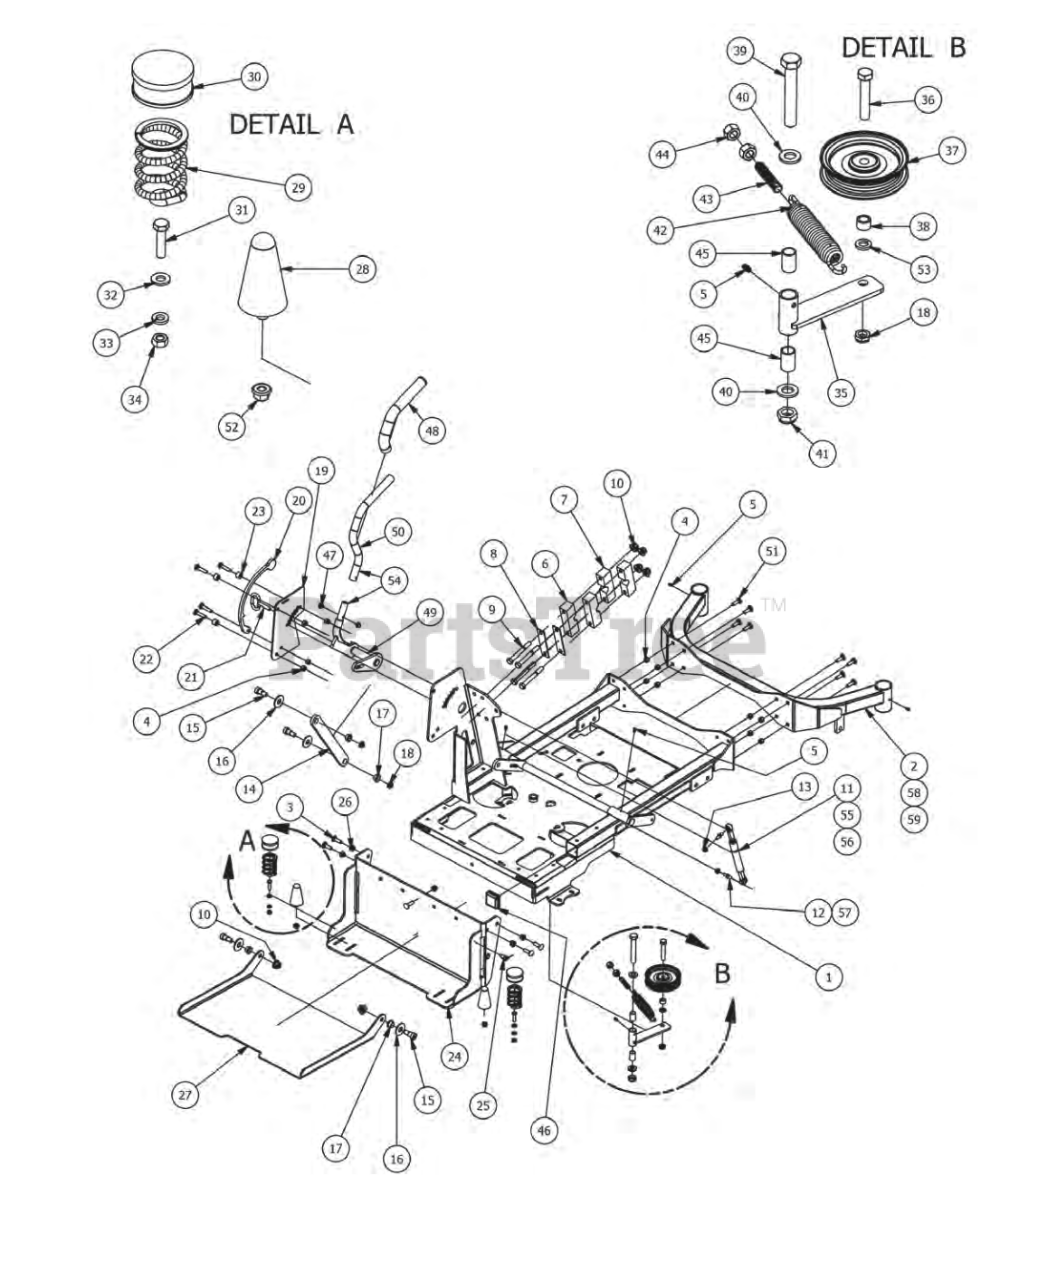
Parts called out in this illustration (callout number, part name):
1	2015 Stand-On Frame
2	48" Front End (2015 Stand-On)
3	3/8" x 1 1/4" Carriage Bolt
4	3/8 Nylock Nut
5	1/4" Press in Grease Fitting
6	Two Piece Pillow Block (Male)
7	Two Piece Pillow Block (Female)
8	Two Piece Pillow Block Strap
9	1/2" x 4" Bolt (Grade 8)
10	1/2-13 Nylon Flange Nut-Orange
11	200 lb Gas Spring- 54" Deck outlaw
12	10mm Damper Ball Stud-Steering
13	5/16" Flange Nut
14	Stand On Flat Linkage Bar
15	5/8" x 5/8" Shoulder Bolt
16	5/8" Flat Washer
17	Bronze Bushing - SF-2024-8
18	1/2" Nylcock Nut (1/2 Jam)
19	2015 Stand-On Adjustment Plate (Bolt On)
20	2015 Stand-On Deck Lever Lock
21	Deck height lever pin
22	3/8 x 1 3/4 Carriage Bolt
23	ACS Spacer 3/4x3/8x1/2
24	Stand Frame Support
25	Deck Height Pin-Stand On-New
26	3/8" Nylock Flange Nut
27	Stand Plate for Stand On
28	Rubber Cone-1621-153
29	Seat Spring
30	Spring Cap Cover
31	5/16 x 1 1/4 Hex Bolt
32	5/16" Flat Washer
33	5/16" Lock Washer
35	Stand-On Pump Idler Bracket
36	1/2" x 2 3/4" Hex Bolt
37	4 3/4" Idler Pulley
38	1/2 x 1/2 Spacer
39	5/8" x 4" Hex Bolt
40	.635 ID Plastic Washer
41	5/8" Nylock (1/2 Jam)
42	2009 Deck/Pump Idler Spring
43	All Thread-pump Idler Tensioner
44	1/2" Hex Nut
45	Idler Retainer bushing
46	2X2 Frame Plug
47	5/16-18 1/2 HWH Bolt-Steering
48	rubber grip
49	Stand-On Deck Lift Lever
50	Stand-On Deck Lift Handle
51	3/8"-16 x 1 1/4" Carriage Bolt
52	5/16" Flange Nut Zinc W/Serrations
53	1/2" Lock Washer
54	Deck Lift Lever Assembly uses parts. 47, 48, 49, & 50
55	250 lb Gas Spring-61" Deck outlaw
56	300 lb Gas Spring-72" Deck outlaw
57	13 mm Damper Ball Stud for 72" Deck only
58	54" Front End (2015 Stand-On)
59	61" Front End (2015 Stand-On)
